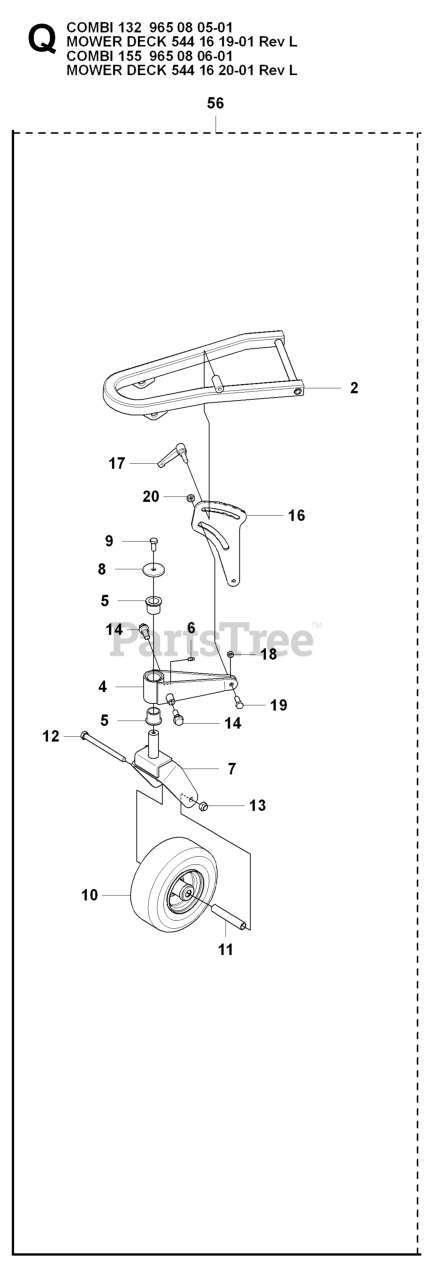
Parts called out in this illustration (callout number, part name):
2	SUPPORTING ARM RIGHT
4	PIVOT WHEEL SUPPORT RIGHT
6	GREASE NIPPLE
7	FORK PIVOT WHEEL
10	TIRE/WHEEL.CASTER.9X3.5-4.SMOO
16	SHEET HEIGHT ADJUSTER
17	TURNING KNOB M 10
18	SLEEVE PIVOT WHEEL SUPPORT
20	NUT
56	WHEEL SUSPENSION RIGHT
